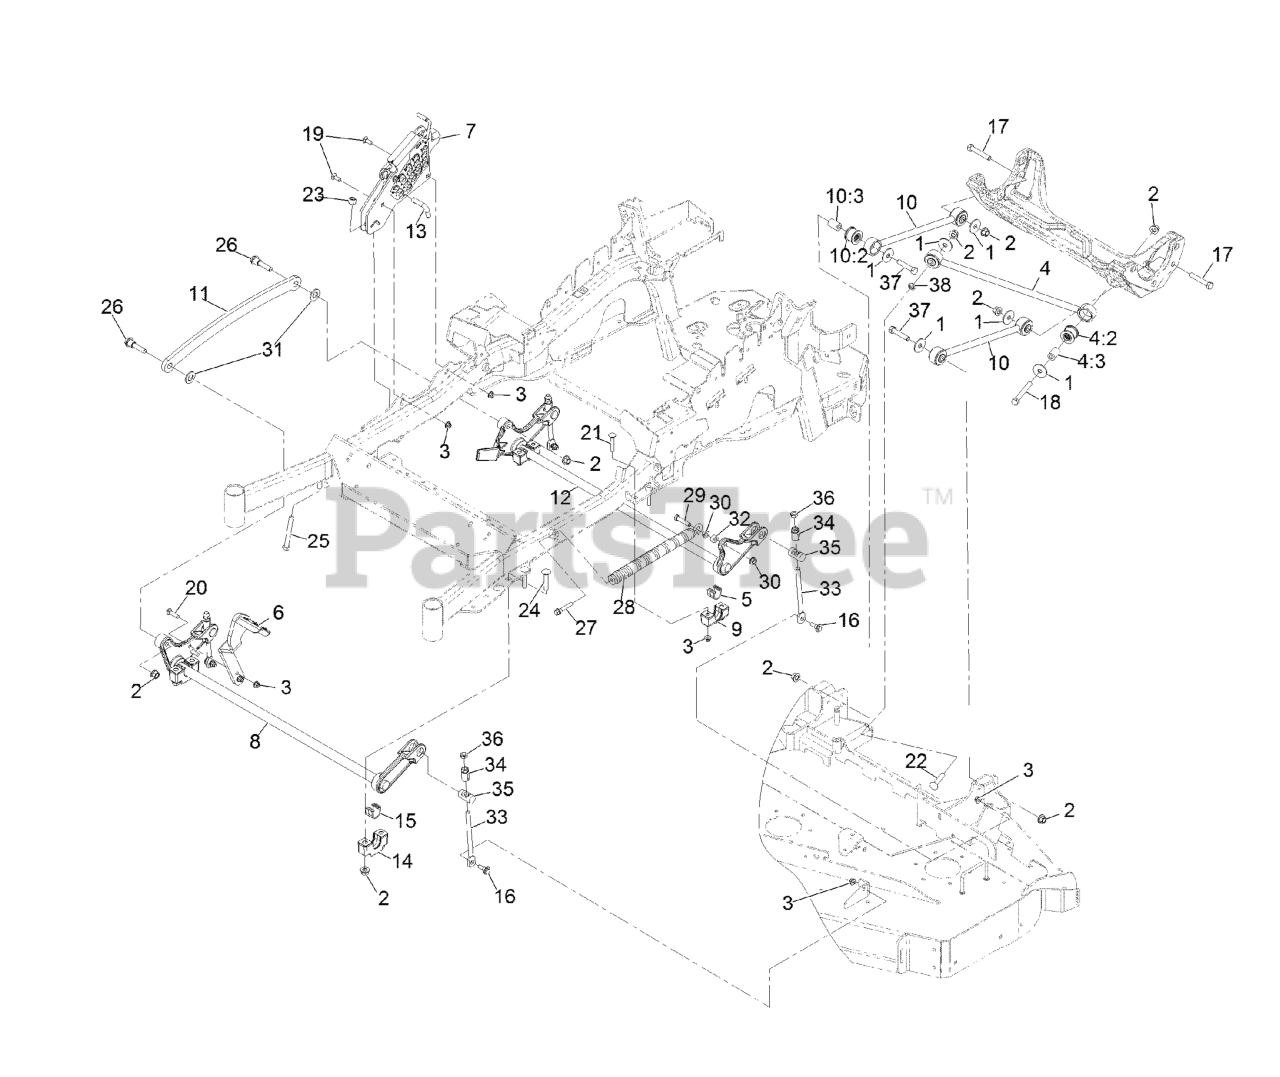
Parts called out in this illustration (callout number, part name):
1	WASHER-THRUST
2	Nut-Lock 1/2-13
3	NUT-HF, NI
4	PANHARD ROD ASM
4:2	BUSHING-SUSPENSION, RUBBER
5	BEARING-CROSS SHAFT, REAR
6	LEVER-FOOT
7	HOC ASM
8	DECKLIFT-FRONT
9	SUPPORT-CROSS SHAFT, BEARING REAR
10	DECK STRUT ASM
10:2	BUSHING-SUSPENSION, RUBBER
11	LINK-LIFT, DECK
12	LIFT-DECK, REAR
13	PIN-HOC
14	SUPPORT-CROSS SHAFT, BEARING
15	BEARING-CROSS SHAFT, FRON
16	SCREW-SHOULDER, HHF
17	SCREW-HH
18	SCREW-HH
19	BOLT-CARR
20	SCREW-CARR
21	Bolt-Carriage 3/8-16 X 2 1/4
22	SCREW-CARR
23	NUT-LOCK, NI
24	Bolt-Carriage 1/2-13 X 2 1/2 Spl Neck
25	BOLT-TAP
26	SCREW-HHF, SHOULDER
27	BOLT-SHOULDER
28	SPRING-EXTENSION
29	SCREW-HH
31	WASHER-FLAT
33	LINK-ADJUSTER, DECK LIFT
34	ADJUSTER-LIFT, DECK
35	TRUNNION
36	NUT-JAM
37	SCREW-HH
38	NUT-PUSH
